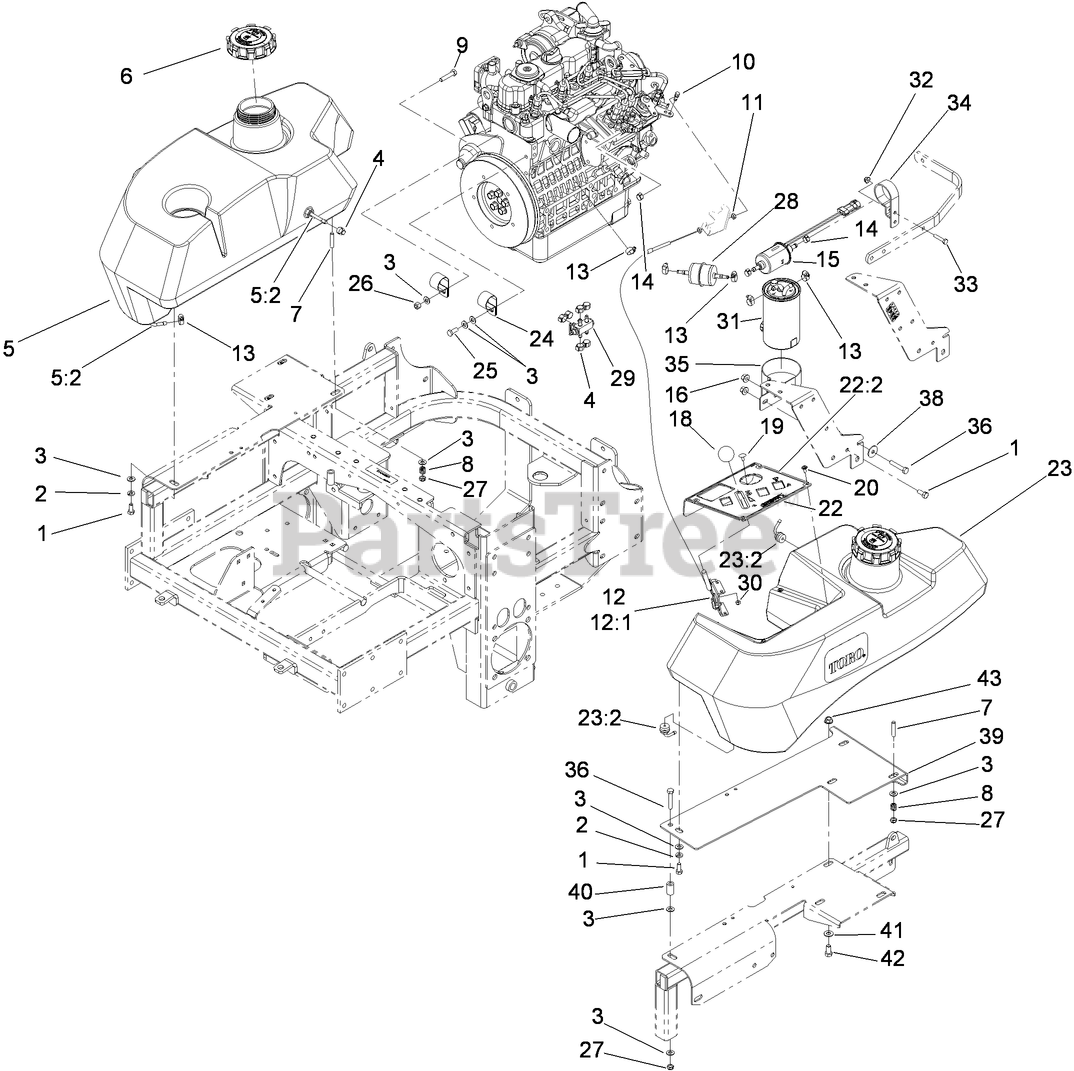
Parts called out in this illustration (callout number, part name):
1	SCREW-HH
2	WASHER-LOCK
3	WASHER-PLAIN
4	CLAMP-HOSE, FUEL
5	RH FUEL TANK ASM
5:2	Fitting-Fuel, Bulkhead
6	BIODIESEL CAP ASM
8	SPRING-TANK, FUEL
9	SCREW-HH
10	SWIVEL-STOP, CABLE
11	NUT-JAM
12	THROTTLE CONTROL ASM
12:1	LEVER-THROTTLE
13	CLAMP-WORM
14	CLAMP-HOSE, FUEL
15	PUMP-FUEL
16	NUT-LOCK, NI
18	KNOB-BALL
19	BOLT-CARR
20	SCREW-PPH
22	CONTROL PANEL ASM
22:2	DECAL-PANEL, CONTROL
23	LH FUEL TANK ASM
23:2	Fitting-Fuel, Bulkhead
24	CLIP-LOOM
25	SCREW-HH
26	NUT-LOCK, NI
27	NUT-LOCK, NI
28	FILTER-INLINE
29	VALVE-FUEL, DUAL FLOW
30	NUT-LOCK, NI
31	ELEMENT-FILTER, FUEL/WATER
32	NUT-HF
33	SCREW-HH
34	BRACKET-PUMP, FUEL
35	BRACKET-FILTER, FUEL
36	SCREW-HH
38	WASHER-FLAT
39	BRACKET-FUEL TANK, LH
40	SPACER
41	WASHER-FLAT
42	SCREW-HH
43	NUT-HHF, WHIZ
